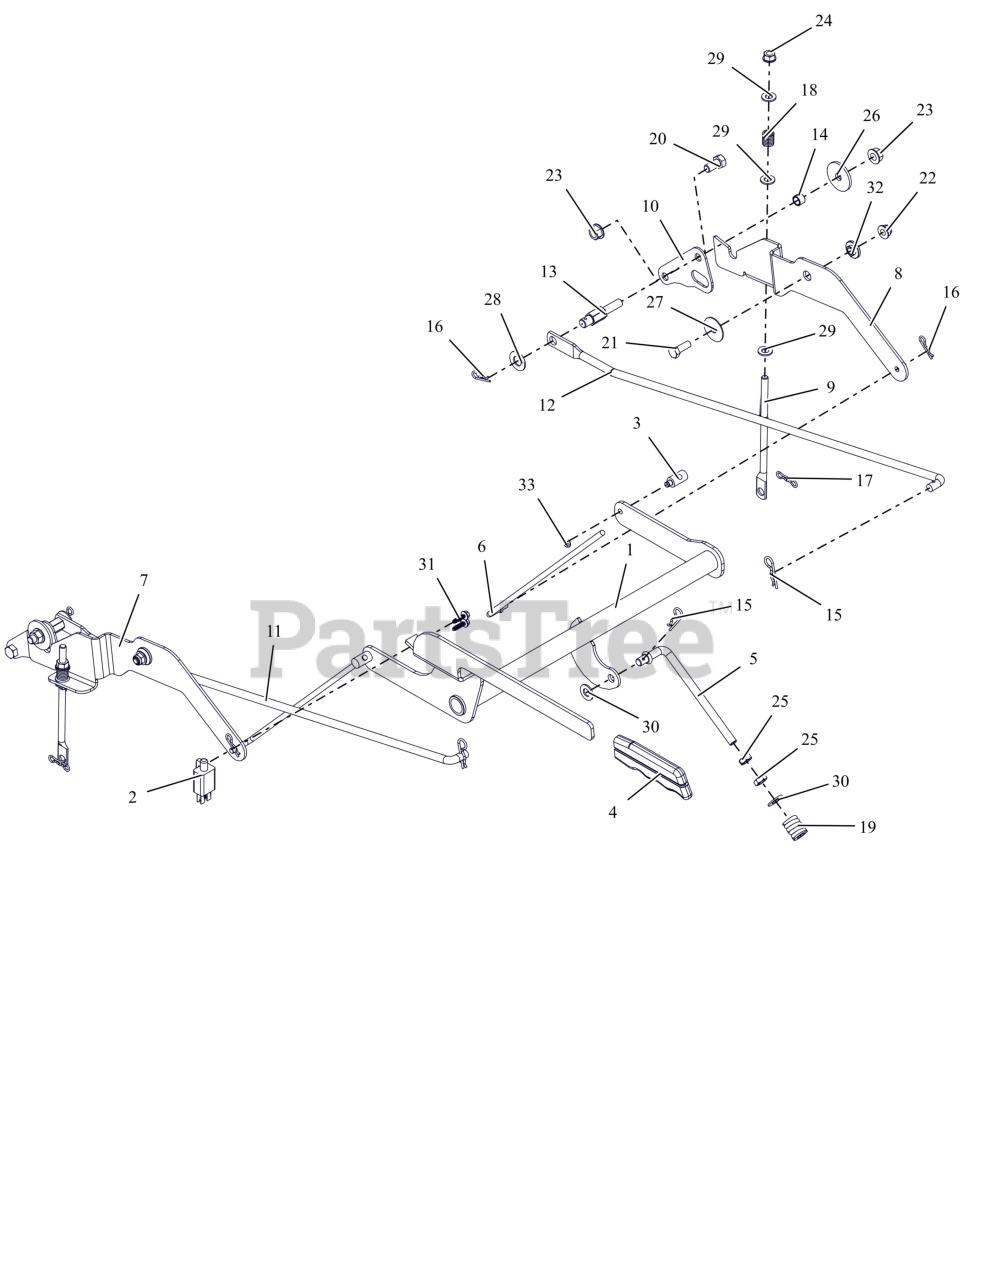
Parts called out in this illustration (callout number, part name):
1	WLDMT, BRAKE LEVER
2	SWITCH- DOUBLE POLE N.O./N.O.
3	TRUNION, 1/4-20
4	GRIP, PARKING BRAKE (GREY)
5	LINK, OVER CENTER, PARKING BRK
6	LINK, BRAKE ARM
7	INTERLOCK, RH BRAKE LINK
8	INTERLOCK, LH BRAKE LINK
9	LINK, BRAKE COG
10	PLATE, TRANSAXLE ADAPTOR
11	LINKAGE, STEERING - RH
12	LINKAGE, STEERING - LH
13	POST, STEERING LINK MOUNTING
14	SPCR, SLV .385X.500X.350
15	PIN, HAIR #203 .09X1.50 ZCC
16	PIN, HAIR #213 .08X1.19 ZCC
17	PIN, BOWTIE #72 ZCC
18	SPRING, COMPRESSION
19	SG-COMP .187X.56X1.62
20	BLT,HEX .38-16X.75 G5 ZCC
21	BLT, HEX .31-18X.875 G5 ZCC
22	NUT,LK-NYL-FLG .31-18 G5ZC120
23	NUT-LK-CTR-FLG .375-16 GF ZCC
24	NUT,LK-CTR-FLG .31-18 GF ZCC
25	NUT-JAM .375-16 G2 ZCC
26	WSHR, FLT .380X1.50X.125 ZCC
27	WSHR, FLT .347X1.254X.048 ZCC
28	WSHR, FLT .505X1.00X.062 ZCC
29	WSHR,FLT .344X.688X.065 ZCC
30	WSHR,FLT .406X.812X.065 ZCC
31	SCR, PLASTITE #12X.75 ZCC
32	BSHG, FLG .325X.499X.26X.88
33	RG-RTNG-EXT .250X.025
